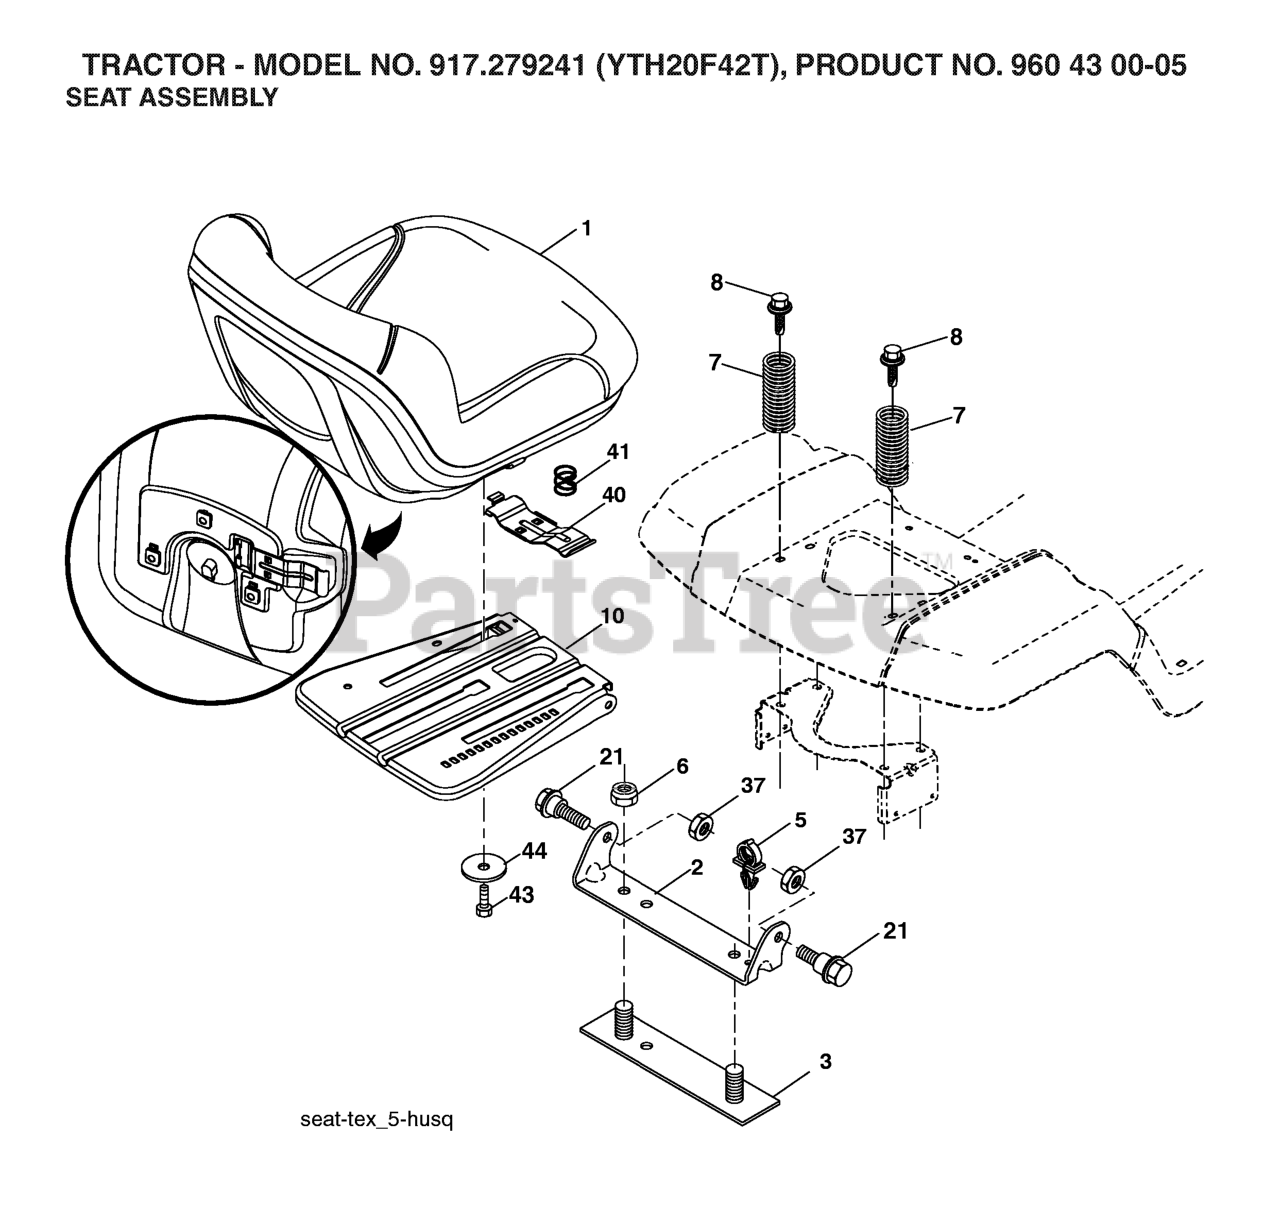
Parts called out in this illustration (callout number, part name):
1	SEAT.TH150.GRY.KB/SL.H
2	BRKT.PIVOT.FENDER
3	STRAP
6	NUT
7	SPRING COMPRESSION
8	BOLT.5/16-18UNCX3/4 W/SEMS.BLK
10	PAN.ASM.SEAT.3PT
21	BOLT.SHOULDER.5/16-18
37	NUT.71038.31-18.HEX.NYLOCK
40	HANDLE.SLIDE.SEAT.TEX.BLACK
41	SPRING.LATCH.SEAT.TEX
44	WASHER 13/32 X 2-3/8 X 12GA
